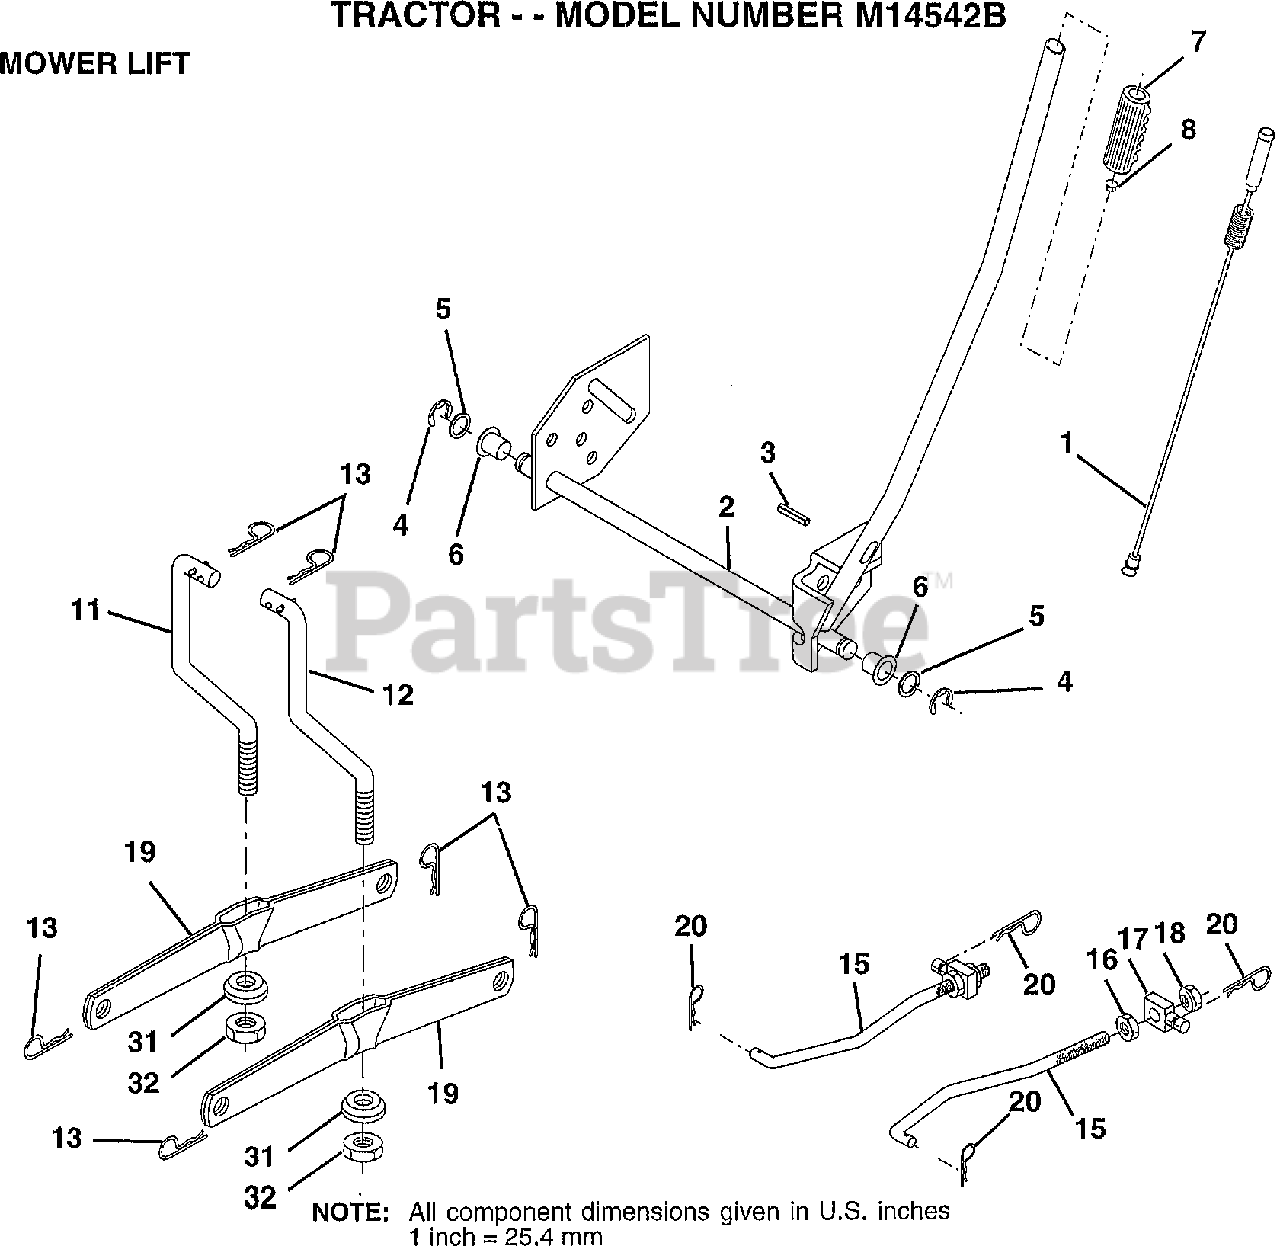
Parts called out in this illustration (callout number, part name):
1	WIRE ASM W.SPRING
2	"SHAFT ASM LIFT,RH"
3	PIN-GROOVE LT
5	WASHER
6	NYLON BEARING
7	GRIP
15	LINK.FRONT
16	NUT
17	TRUNION
18	NUT.LK.W/WSH.1/2.
19	ARM SUSP REAR
20	RETAINER.SPRING
31	BEARING PVT LH
32	NUT.CROWNLOCK.3/8
